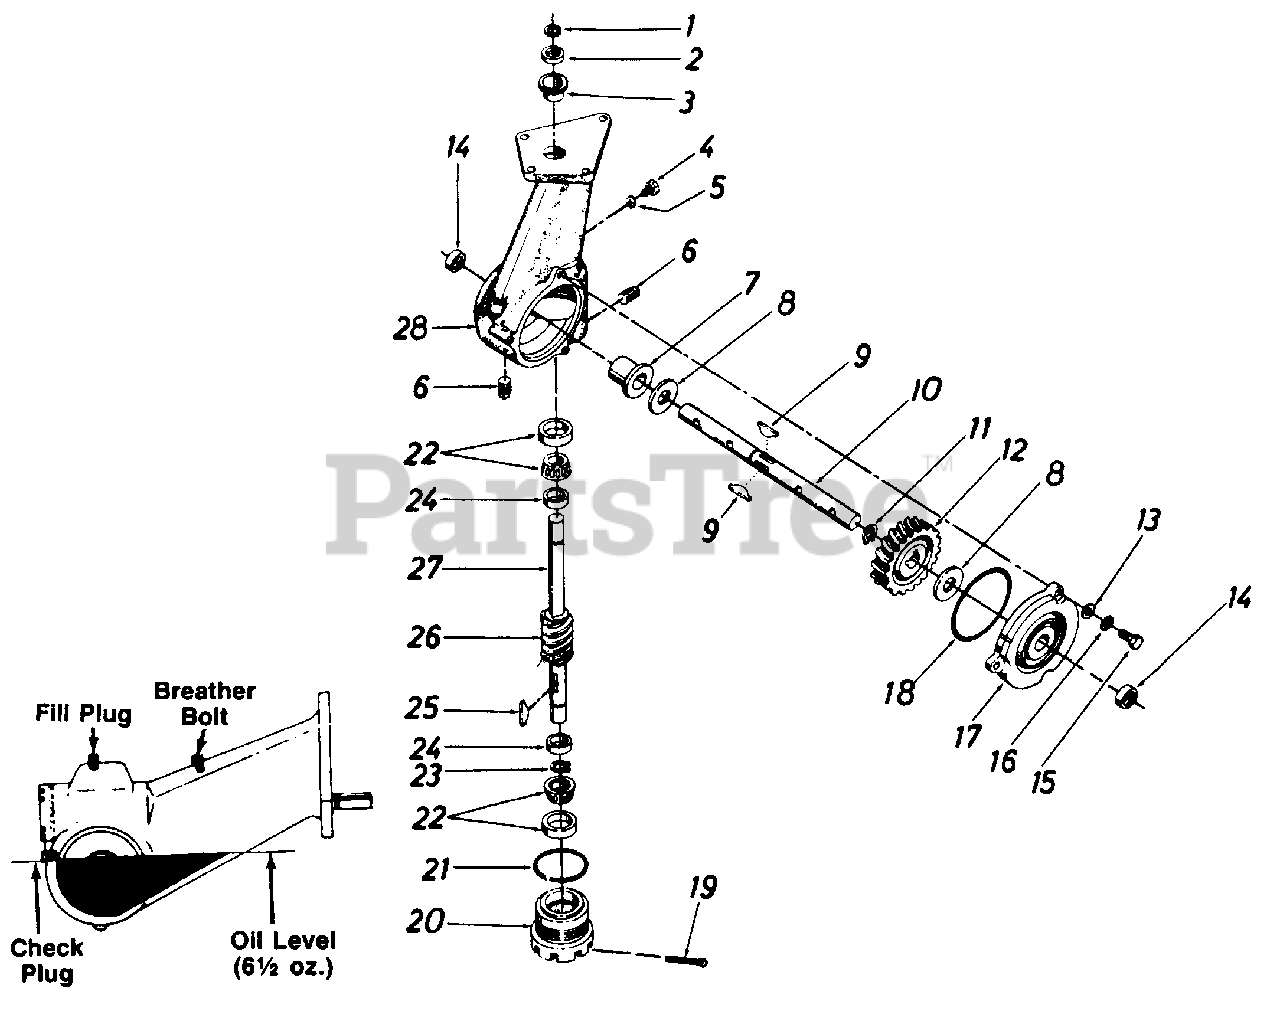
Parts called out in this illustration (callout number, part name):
1	Snap Ring .75" Dia. Shaft
2	Oil Seal .75" Dia. Shaft
3	Sleeve Brg. .752" x .878" x 1.0"
4	Hex Wash. Self-Tap Scr.
5	External L-Wash. 1/4" l.D.
6	Sq. Hd. Pipe Plug 3/8" Thd.
7	Flange Brg. 1.0" l.D.
8	Fl-Wash. 1.0" x 1.62" x .095
9	#91 Woodruff Key 1/4 x 3/4" Dia.
10	Tine Shaft 1.0" Dia.
11	Snap Ring-1.0" Dia. Shaft
12	Worm Wheel
13	L-Wash. 5/16" l.D.
14	Oil Seal Double Lip 1.0" Shaft
15	Hex Scr. 5/16-18 x .88" Lg.
16	Wash.Flat Toothed
17	Bearing Cap with Bearing
18	O-Ring 3.62" x 3.88n
19	Coter Pin 1/8" Dia. x ,75n
20	Bearing Adjustment Cap
21	O-Ring 2.12" x 2.28"
22	Roller Bearing Ass'y. .75 I.D.
23	Snap Ring .755" Dia. Shaft
24	Spacer .755 I.D. x 1.265 O.D.
25	#9 Hi-Pro Key 3/16 x .75" Dia.
27	Worm Shaft
28	Transmission Case
